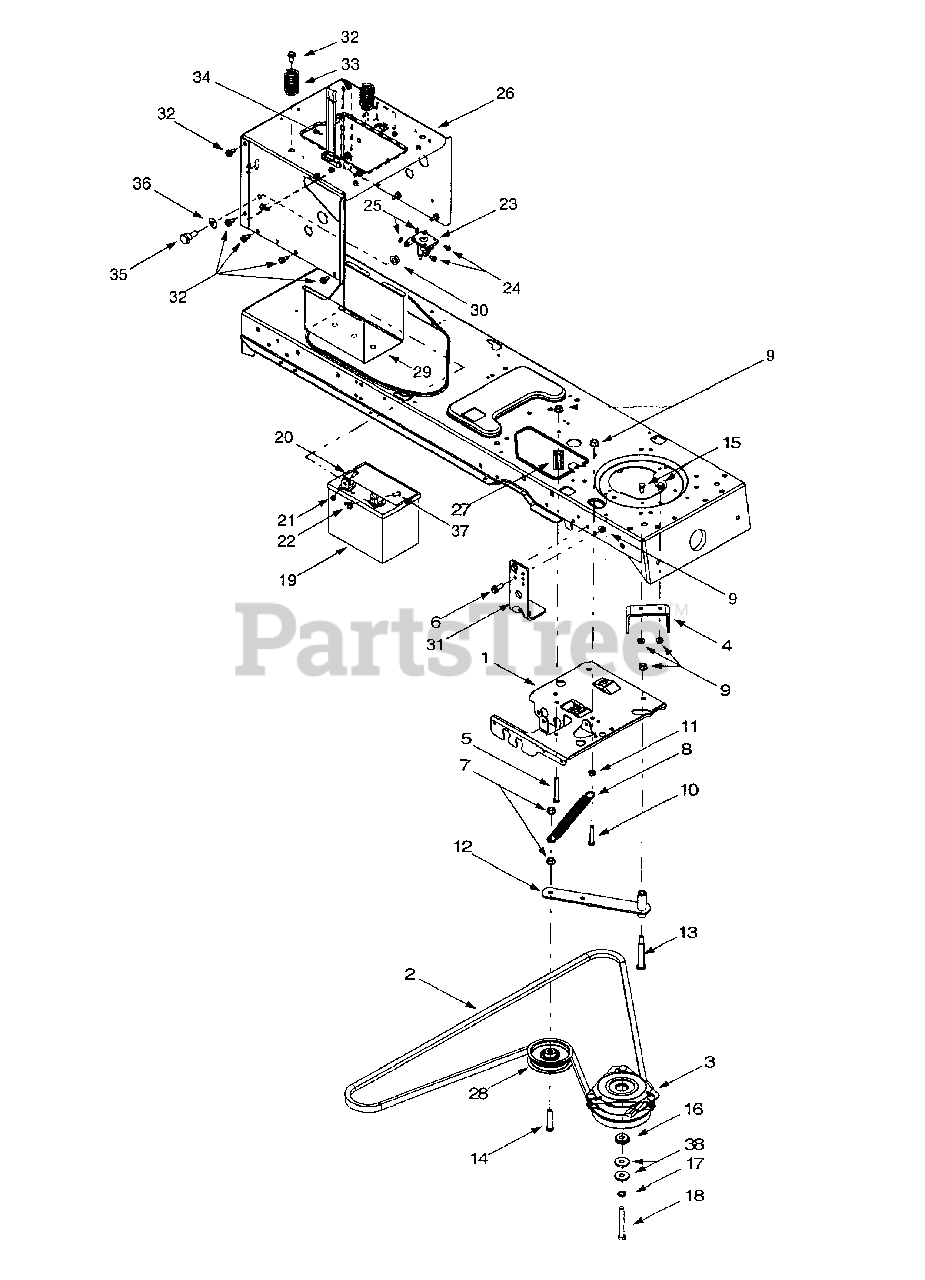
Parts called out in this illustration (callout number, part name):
2	PTO Belt
3	Electric PTO Clutch
6	Hex Head Washer Screw, 5/16-18 x .875
7	Flange Lock Nut, 3/8-16
8	Extension Spring, .62 x 5.62
9	Flange Lock Nut, 5/16-18
10	Hex Cap Screw, 5/16-18 x 1.75
11	Hex Nut, 5/16-18
14	Hex Cap Screw, 3/8-16 x 2.0
15	Hex Cap Screw, 5/16-18 x .625
16	Shoulder Spacer, 1.38 x .445 x .36
17	Lock Washer, 7/16
18	Hex Cap Screw, 7/16-20 x 3.25 (Grade 5)
19	12-volt Battery, 270 CCA
20	Hex Cap Screw, 1/4-20 x .62
21	Hex Sems Nut, 1/4-20
22	Wing Nut, 1/4-20
23	Solenoid, 12-Volt, 100 Amp
24	Self Tapping Screw, 1/4-20 x .5
25	Lock Washer, 1/4
28	Idler Pulley, 3.5
32	Self Tapping Screw, 5/16-18 x .625
33	Compression Spring, 1.28 x 3.5
34	Battery Strap
35	Shoulder Screw, .625 x .5, 7/16-20
36	Bell Washer, .45 x 1.0 x .062
37	Shoulder Screw, 1/4-20, .25 x .15
38	Flat Washer, .45 x 1.25 x .164
